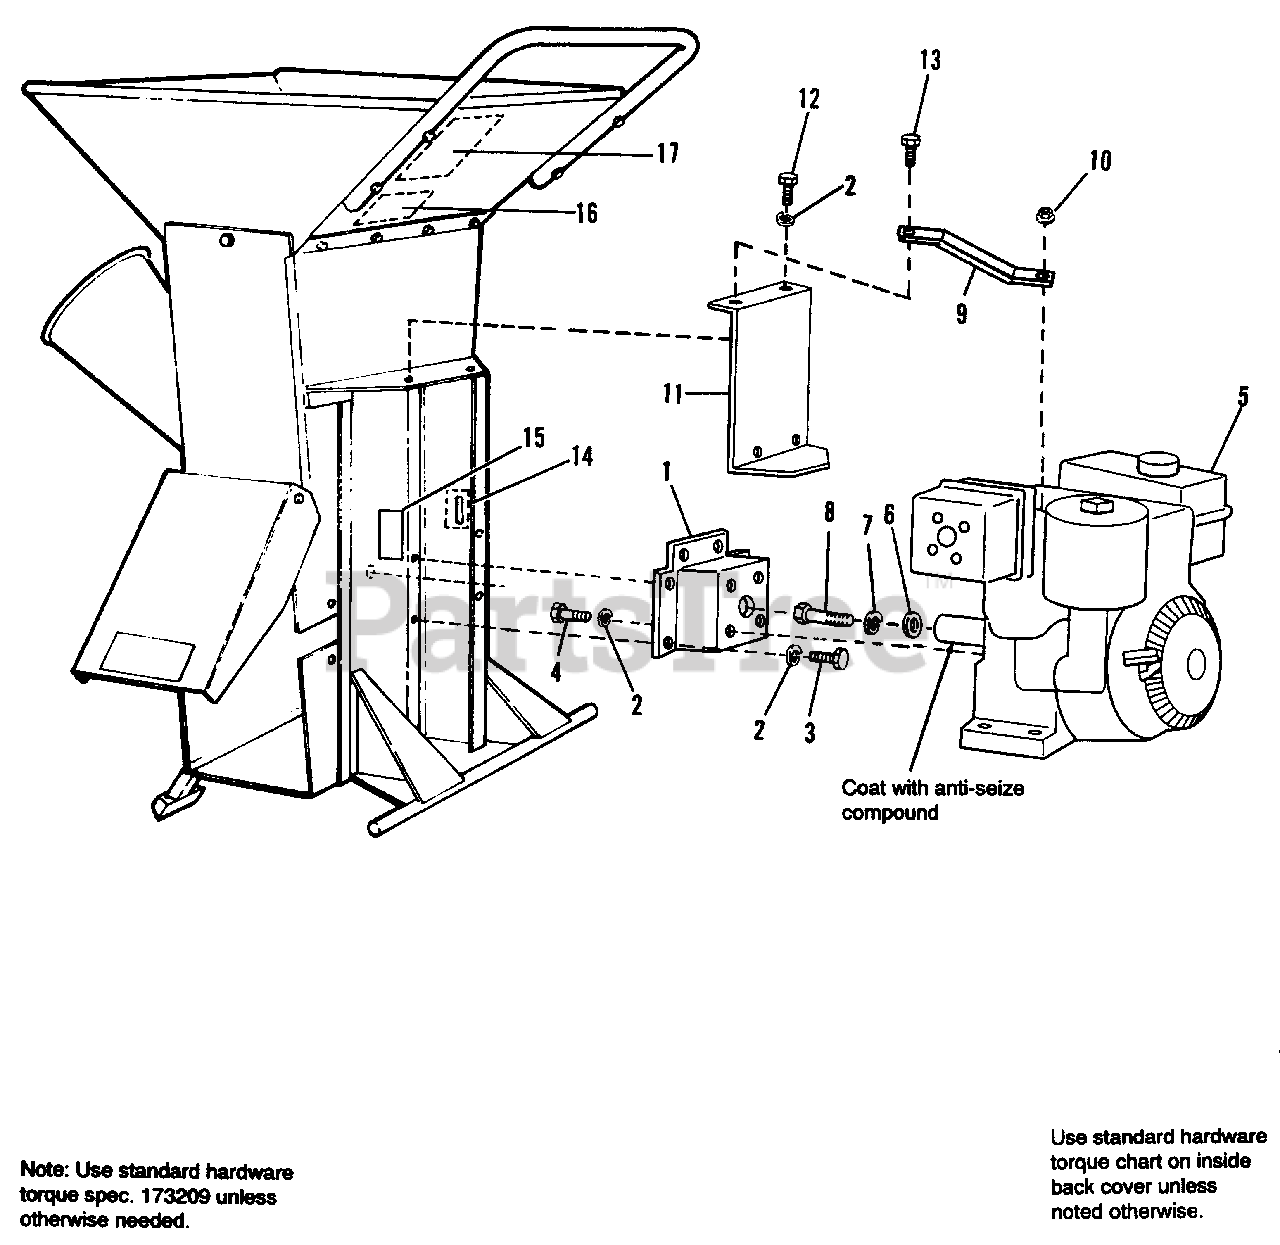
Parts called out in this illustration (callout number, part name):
1	SUPPORT & COVER ASSY.
2	LOCKWASHER, 5/16
3	CAPSCREW, Hex, 5/16-18 x 3/4, Gr.5
4	CAPSCREW, Hex, 5/16-24 x 3/4, Gr.5
5	ENGINE, 5 HP, Briggs & Stratton
6	WASHER, Plain, 13/32 x 7/8 x 5/64
7	LOCKWASHER, 3/8
8	CAPSCREW, Hex, 3/8-24 x 1-1/4, Gr. 8
9	STRAP, Engine Support
10	NUT, Hex, Flange Whiz, 5/16-18
12	CAPSCREW, Hex, 5/16-18 x 1/2, Gr. 5
13	SCREW, Taptite, 5/16-24 x 3/4
14	I.D. PLATE
15	DECAL, Patent
16	DECAL, Danger
17	DECAL, Caution/Operate
